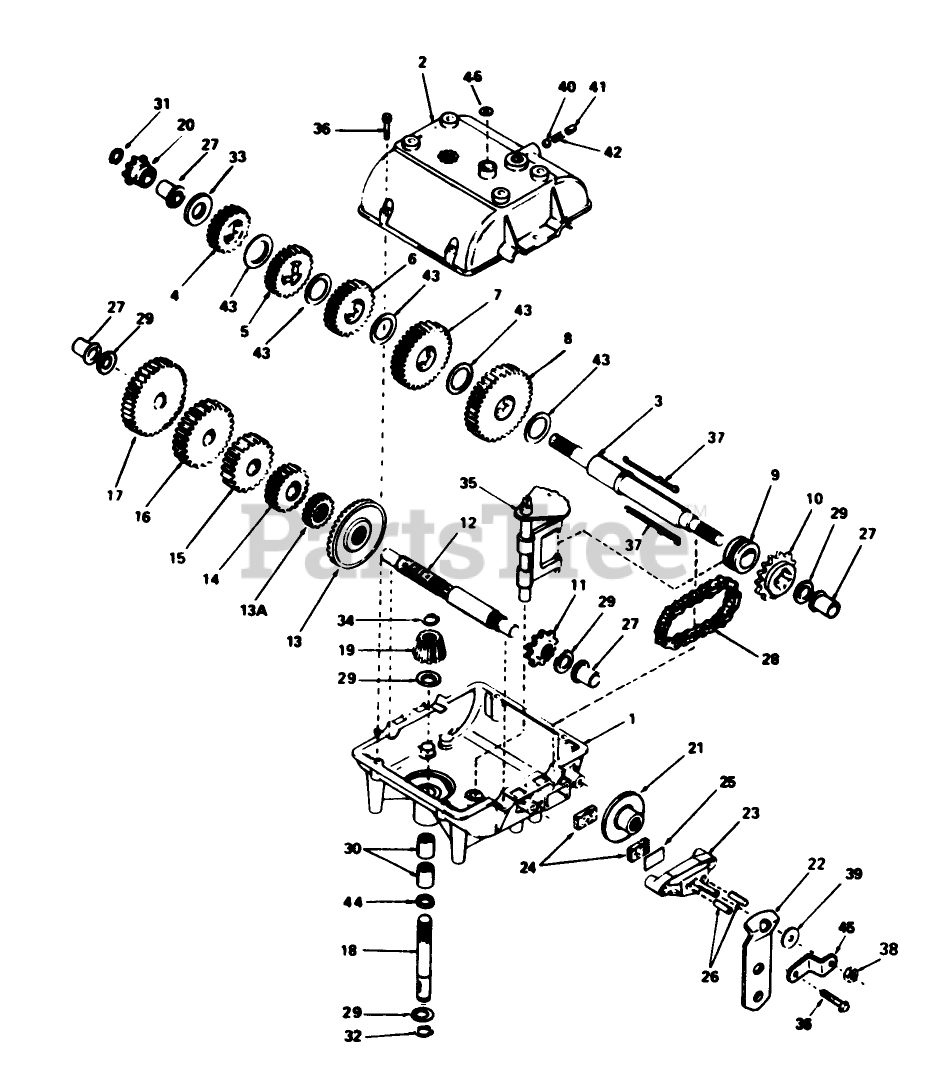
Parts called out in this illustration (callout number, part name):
1	Case-Transmission
2	Cover-Transmission
3	Shaft-Output
4	Gear-Spur 20 teeth
5	Gear-Spur (22 teeth)
6	Gear-Spur, 25 Teeth
7	Gear-Spur, 30 Teeth
8	Gear-Spur, 35 Teeth
9	Collar-Shift
10	Sprocket-18 Teeth
11	Sprocket-9 Teeth
12	Countershaft
13	Gear-Bevel (42 Teeth)
13A	Gear-Spur 15 Teeth
14	Gear-Spur, 20 Teeth
15	Gear-Spur, 25 Teeth
16	Gear-Spur (28 teeth)
17	Gear-Spur (30 teeth)
18	Shaft-Input
19	Bevel Pinion-Input
20	Sprocket (8Teeth)
22	Lever-Brake
23	Nozzle-Carburetor
24	Brake Pad
25	Brake Pad Plate
26	Dowel Pin
27	Bushing-Flange
28	Chain-Roller #41
29	Washer
30	Bearing-Needle
31	Piston Asm (.020 O S)
32	Ring-Snap
33	Washer
34	Ring-Retainer
35	Rod and Fork ASM
36	Ring Set (.020 O S)
38	Locknut
39	Washer
40	Ball-Steel
41	Screw-Set
42	Spring
43	Washer
44	O Ring
45	Bracket
46	Cut Seal-Square
